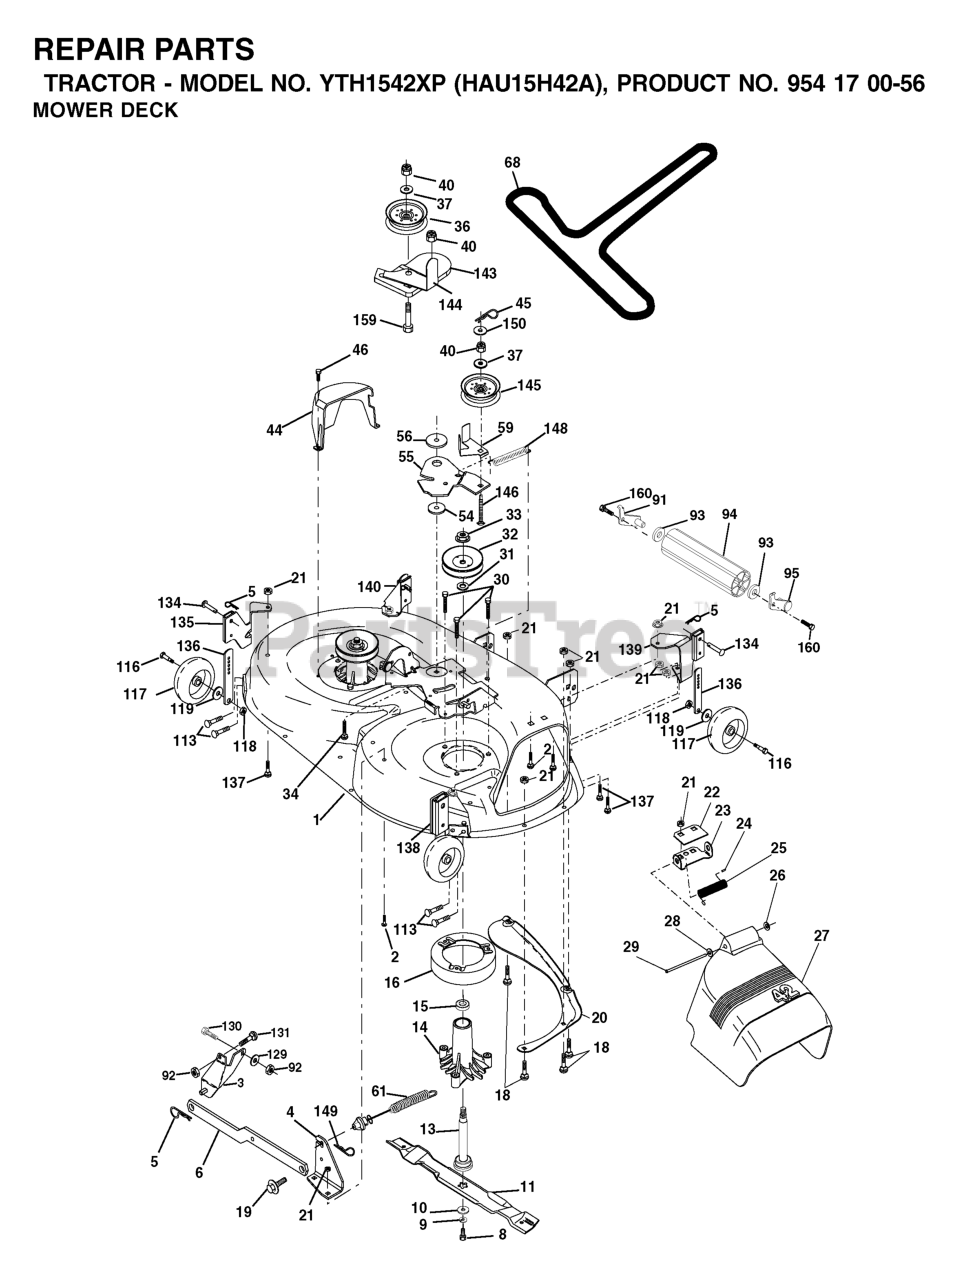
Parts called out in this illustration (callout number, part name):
1	DECK, 42"
2	RP BOLT 5/16-18 X3/4 ZN/YEL GR
3	BRKT ASM SWAY BAR
4	BRACKET ASM DECK 42"
5	RETAINER-SPRNG RB
6	REAR SUSP ARM
8	BLADE BOLT
9	LOCKWASHER
10	WASHER.BLADE
11	Blade Mower 42" High Perf.
13	SHAFT ASM VENT
14	HOUSING.MANDREL.VENTED (MACHD)
16	STRIPPER.MANDREL.ROUND.BLACK
18	BOLT
19	BOLT SHD 5/16-18
20	BAFFLE.VORTEX
21	LOCKNUT
22	STIFFENER BRACKET
23	DEFLECTOR BRACKET
24	CAP-SLEEVE LT
25	SPRING TORSION
26	NUT PUSH M
27	SHIELD DEFLECTOR
28	Washer 11/32 x 5/8 x 16 Ga SD
29	ROD.HINGE
30	SCREW, WASHER HEAD
31	WASHER
32	PULLEY MANDREL
33	NUT, FLG TOPLOCK 9/16"
36	PULLEY.IDLER.FLAT
37	WASHER
44	GUARD MANDREL LH BLACK
45	RETAINER M
46	SCREW.1/4-20X5/8
54	HARDENED WASHER
55	ARM IDLER 42"
56	SPACER RETAINER
59	GUARD TUV IDLER
61	SPRING EXT ELEC CLUTCH
68	V-BELT PRIMARY 42"
91	BRACKET ASM, ROLLER (L)
92	NUT
93	Washer 1 17/32 X 7/8 X 16 Ga
94	NOSE ROLLER
95	BRACKET ASM, ROLLER
113	SCREW 5/16"
116	BOLT, SHOULDER
117	WHEEL GAGE DONUT
118	LOCKNUT
119	WASHER.5/16.FLAT.STE.STD.
129	WASHER
130	BOLT
131	BOLT D
134	RIVET.PIN.HEAD.YELLOW.
135	BRACKET ASM, WHEEL
136	BAR.ADJUST.WHEEL.ANTI.SCALP.BL
137	BOLT.CARR.5/16-18X5/8.SHORT
138	BRACKET.ASM.WHL.GA.R.RH.42".GR
139	BRACKET ASM, WHEEL
140	BRACKET ASM, WHEEL
143	BRKT ARM IDLER 42"
144	KEEPER BELT 42" CLUTCH
145	PULLEY.IDLER.FLAT.PLATED
146	BOLT, CARRIAGE IDLER BLACK
148	IDLER RETURN SPRING
149	SPRING.RETAINER.YELLOW.ZINC
150	WASHER PM
159	BOLT
160	SCREW 3/8-16X3/4
